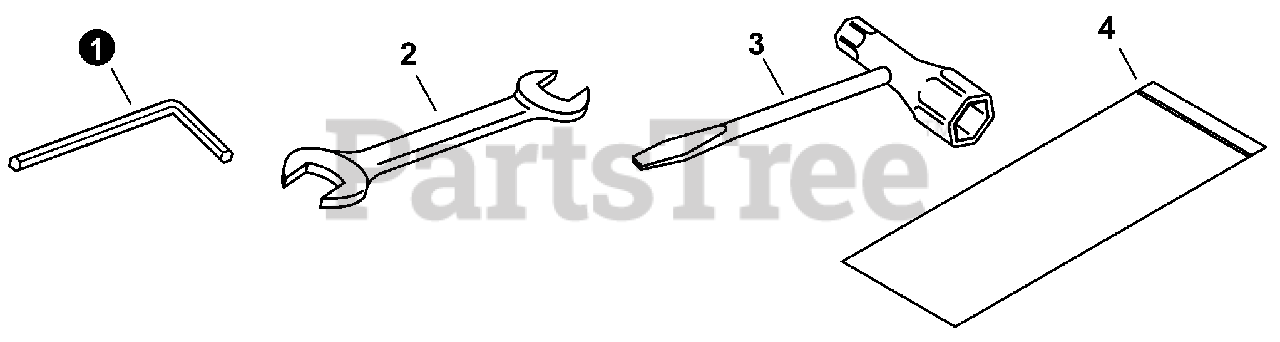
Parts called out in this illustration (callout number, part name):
1	WRENCH, ALLEN 4 MM
2	SPANNER 8x10
3	T-WRENCH 13x19 MM
4	BAG, TOOL
